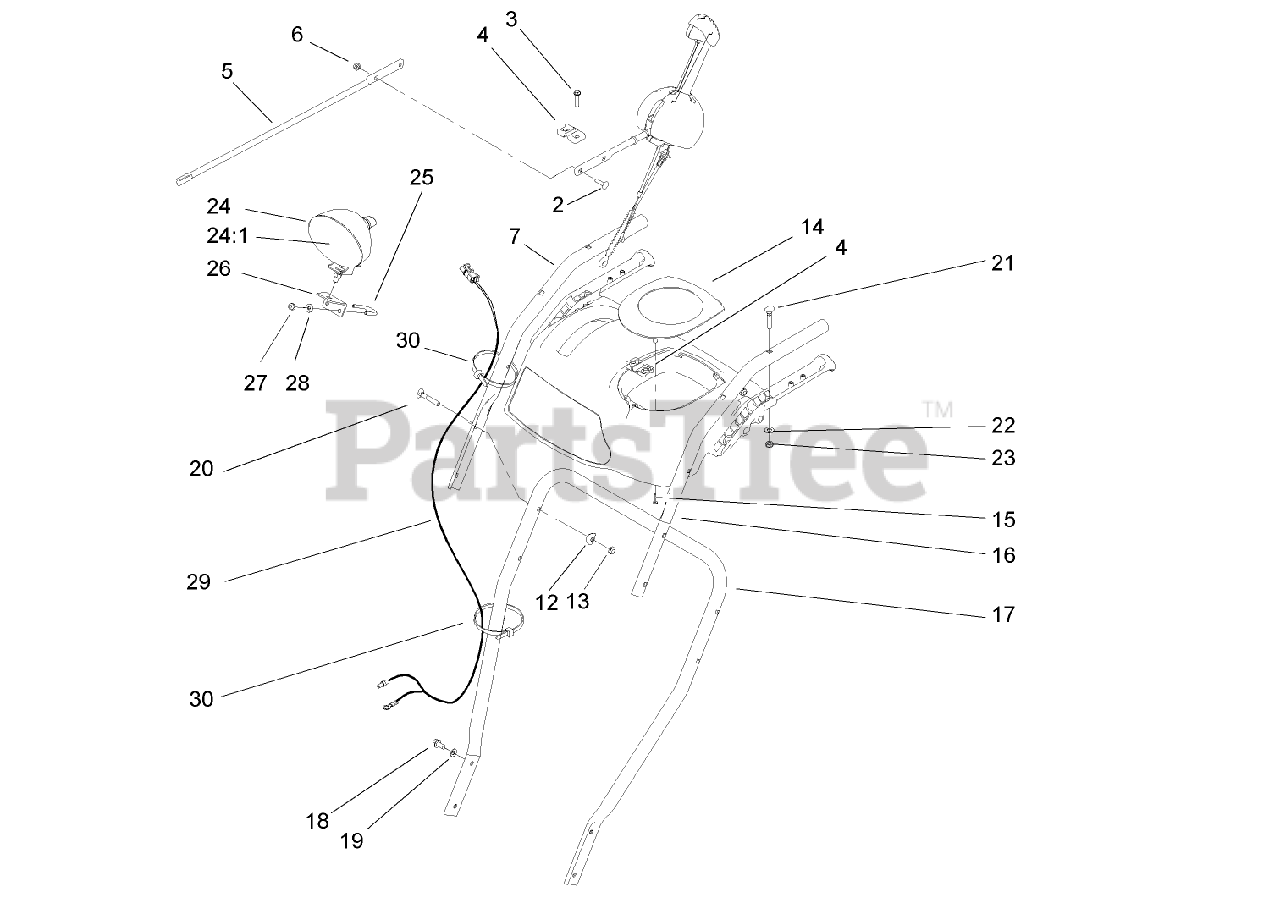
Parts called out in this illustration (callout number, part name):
2	SCREW-CARR
3	SCREW-PLASTITE
4	SUPPORT-ROD
5	ROD-CHUTE, FRONT
6	NUT-LOCK, NI
7	HANDLE-UPPER, RH
12	WASHER
13	NUT-LOCK, NI
14	COVER-PANEL, CONTROL
15	SCREW-PPH
17	HANDLE-LOWER
18	SCREW-HWHTF
19	WASHER-BELLEVILLE
20	SCREW-HANDLE
21	SCREW-HANDLE
22	WASHER-FLAT
23	NUT-LOCK, NI
24	HEADLAMP ASM
24:1	LAMP-12 VOLT
26	BRACKET-LIGHT
27	NUT-LOCK, NI
28	WASHER-FLAT
29	HARNESS-WIRE
30	TIE-CABLE
